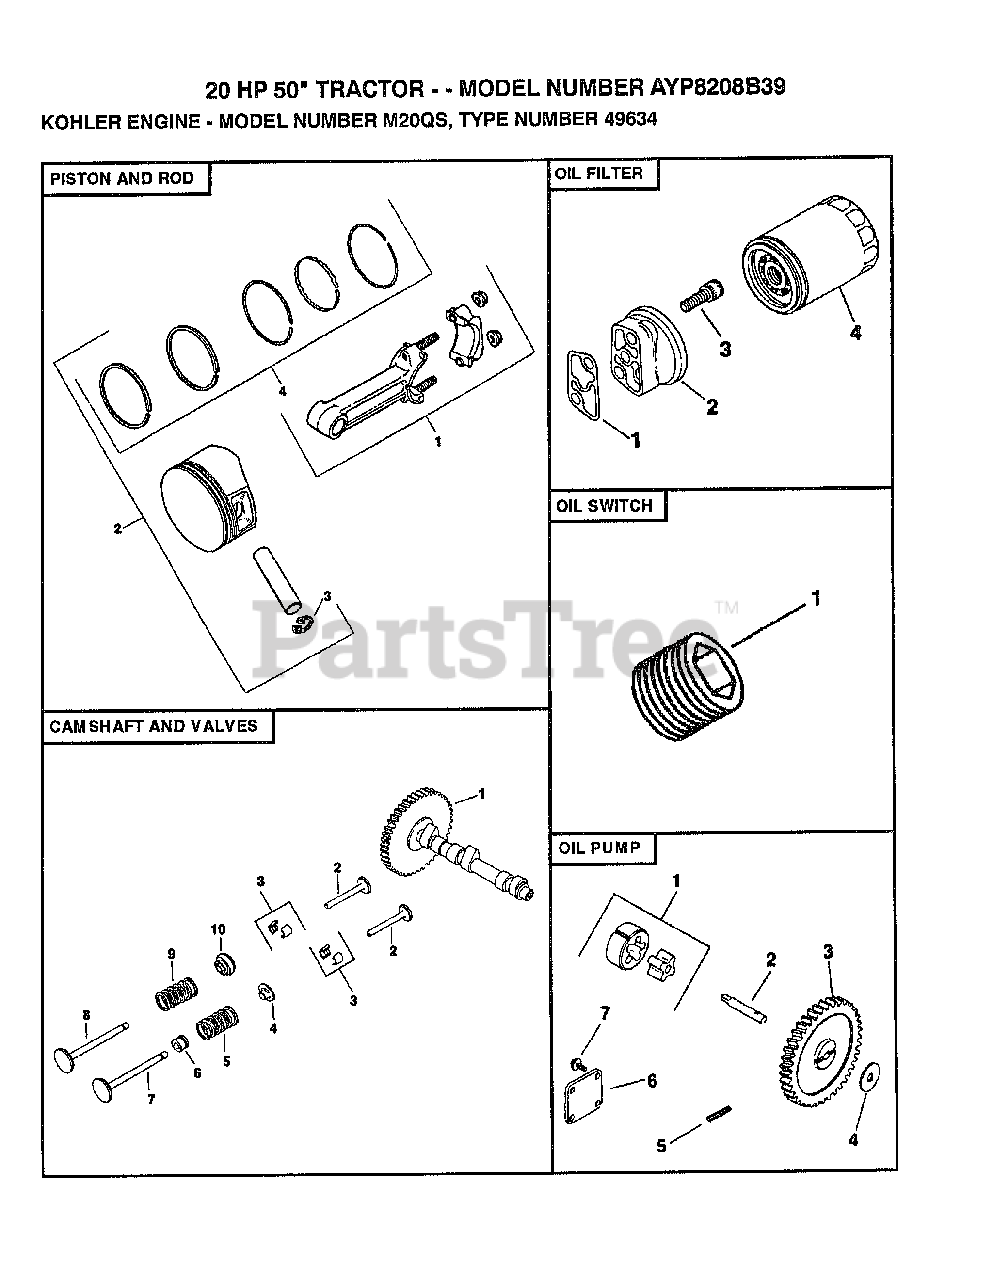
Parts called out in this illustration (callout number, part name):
1	CONNECTING ROD, STANDARD
1	CONNECTING ROD
1	PLUG
2	PISTON WITH RING SET, STANDARD
2	PISTON WITH RING SET .003"
2	PISTON WITH RING SET .010"
2	PISTON WITH RING SET .020"
2	PISTON WITH RING SET .030"
2	ADAPTER, OIL FILTER
2	SHAFT OIL PUMP
3	RETAINER, PISTON PIN
3	SCREW
3	GEAR OIL PUMP
4	RING SET, .003"
4	RING SET, .010"
4	RING SET, 020"
4	RING SET, .030"
4	RETAINER, INTAKE VALVE
5	PIN, ROLL
6	COVER OIL PUMP
7	VALVE, INTAKE
7	SCREW
